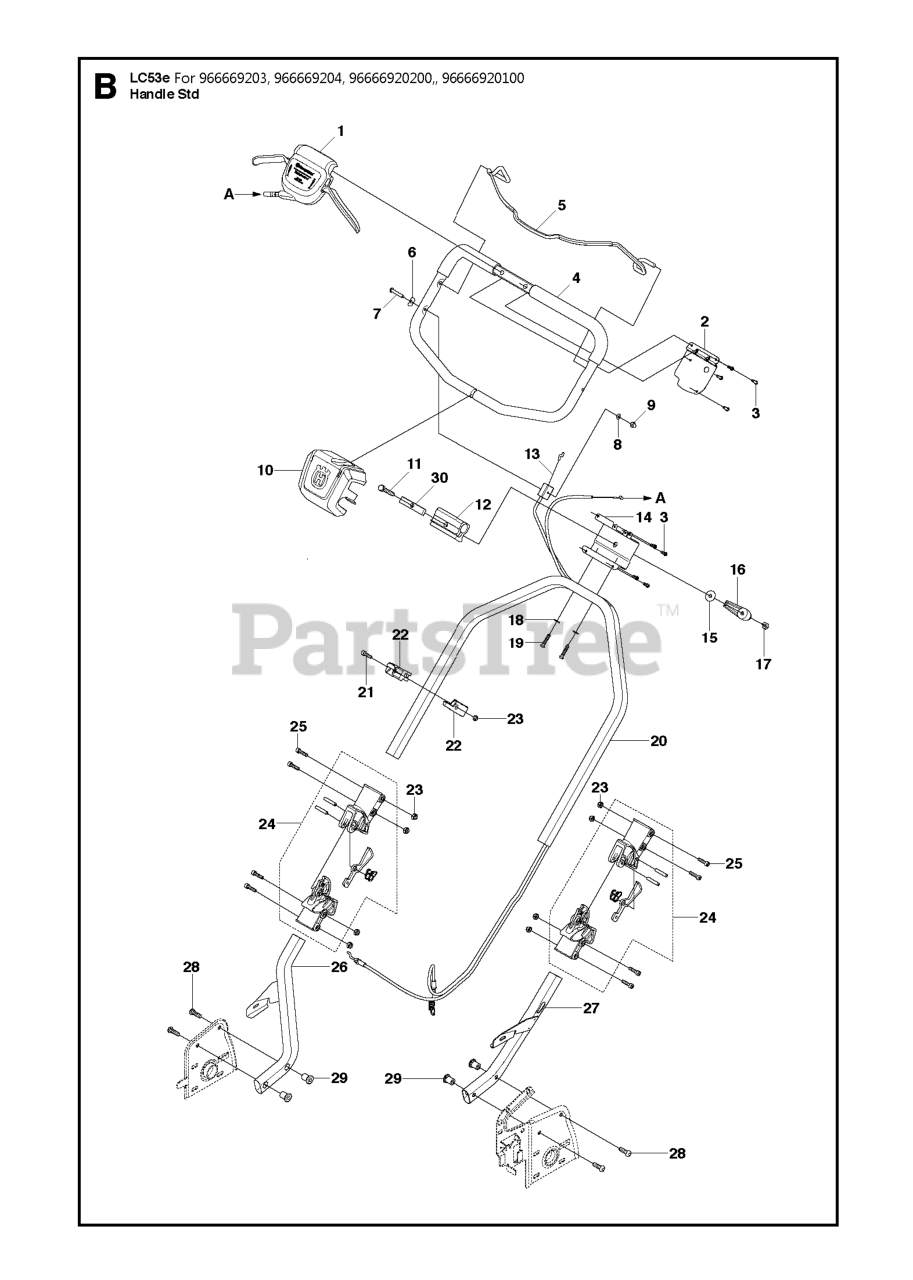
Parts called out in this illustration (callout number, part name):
8	WASHER - M6
15	WASHER - 25X8.5X2.3
21	SCREW MC6S 6X20
25	REPL BY 725 53 74-55
